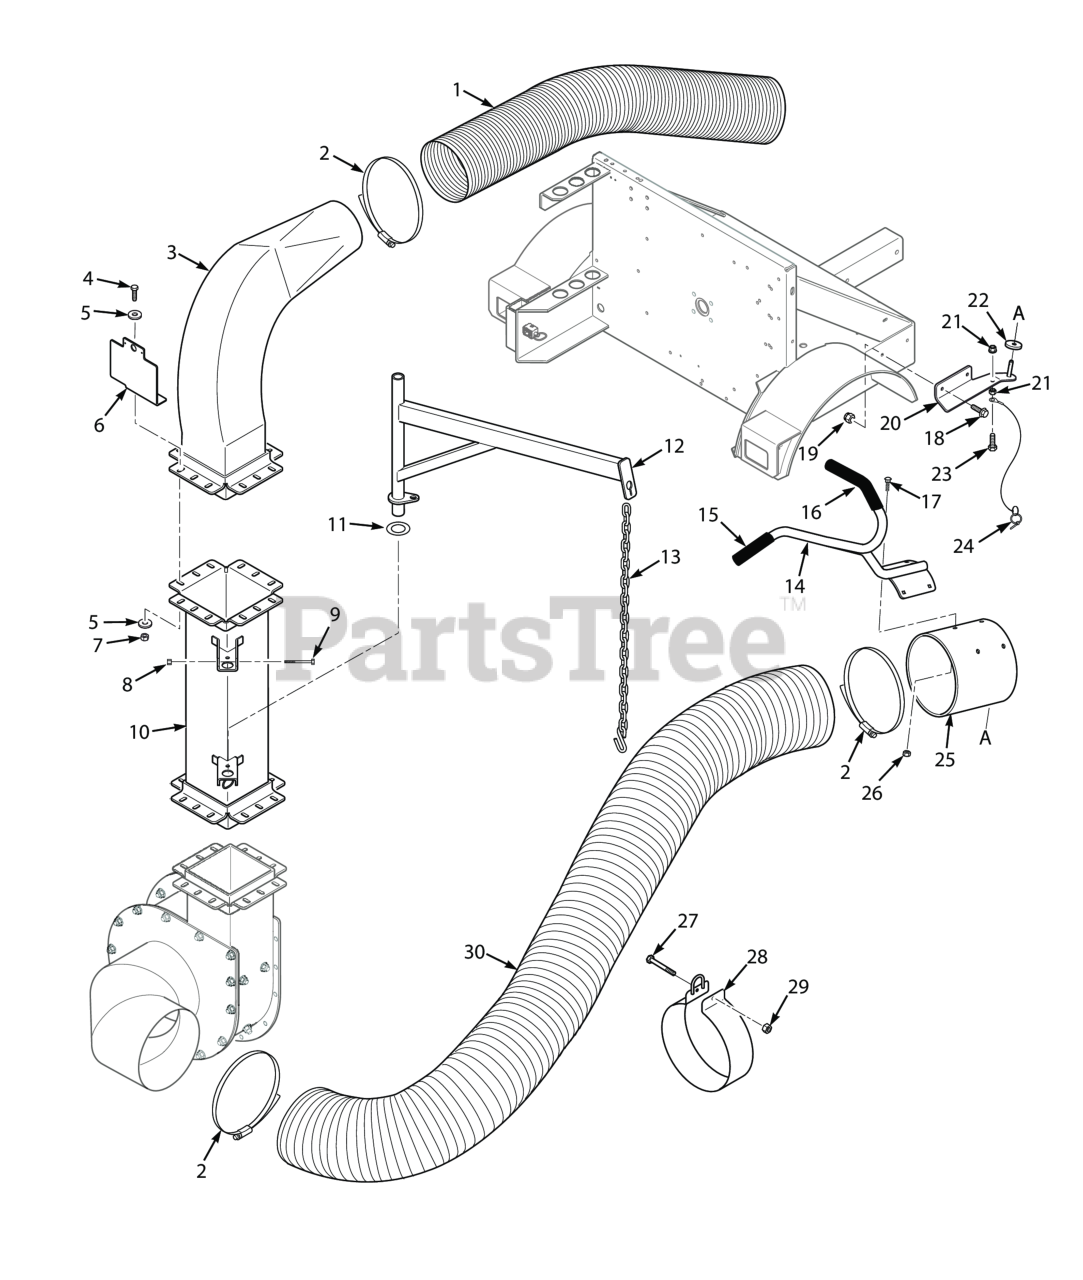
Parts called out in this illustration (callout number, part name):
1	Hose, Clear Poly 12" x 84"
2	Strap, Ratchet- 66 x 1"
3	Elbow, Exhaust - TLB25
4	Bolt, Hex Head 1/2-13 x 1-1/2", (STT-52 & STTII-52)
5	Flat Washer, 1/2 (.562 x 1.375 x .109)
6	Bracket, License Plate
7	HEX LOCKNUT, ELASTIC STOP, 1/2-13
8	HEX, NUT, ELASTIC STOP LOCK, 1/4-20
9	Bolt, Hex Head 1/4-20 x 4"
10	Stack Assembly w/Decals
11	Disk, Anti-Friction
12	Boom Weldment
13	Chain w/2-Hooks
14	Handle w/Grips
15	Grip, Handle 1-1/4" x 6"
16	Grip, Handle 1-1/4" x 20"
17	Carriage Bolt, 3/8-16 x 1.0"
18	Bolt, Hex Head Serrated Flange 3/8-16 x 3/4"
19	NUT, 3/8-16 SERRATED FLANGE HEX HEAD
20	Hose Holder Weldment
21	Nut, Serrated Flange 5/16-18 (Right Front Engine Mounting, Briggs and Kohler Only)
22	Washer, Rubber
23	Bolt, Hex Head 5/16-18 x 1-1/2" (Right Front Engine Mounting, Briggs and Kohler Only)
24	Quick Pin Assembly w/Lanyard
25	Nozzle w/Decal
26	HEX NUT, ELASTIC STOP LOCK, 3/8-16
27	Bolt, Hex Head 5/16-18 x 3.00"
28	Band, Hose Support - 16"
29	HEX NUT, ELASTIC STOP LOCK, 5/16-18
30	Hose, 16" x 84" - .045 P.U. w/Wire
